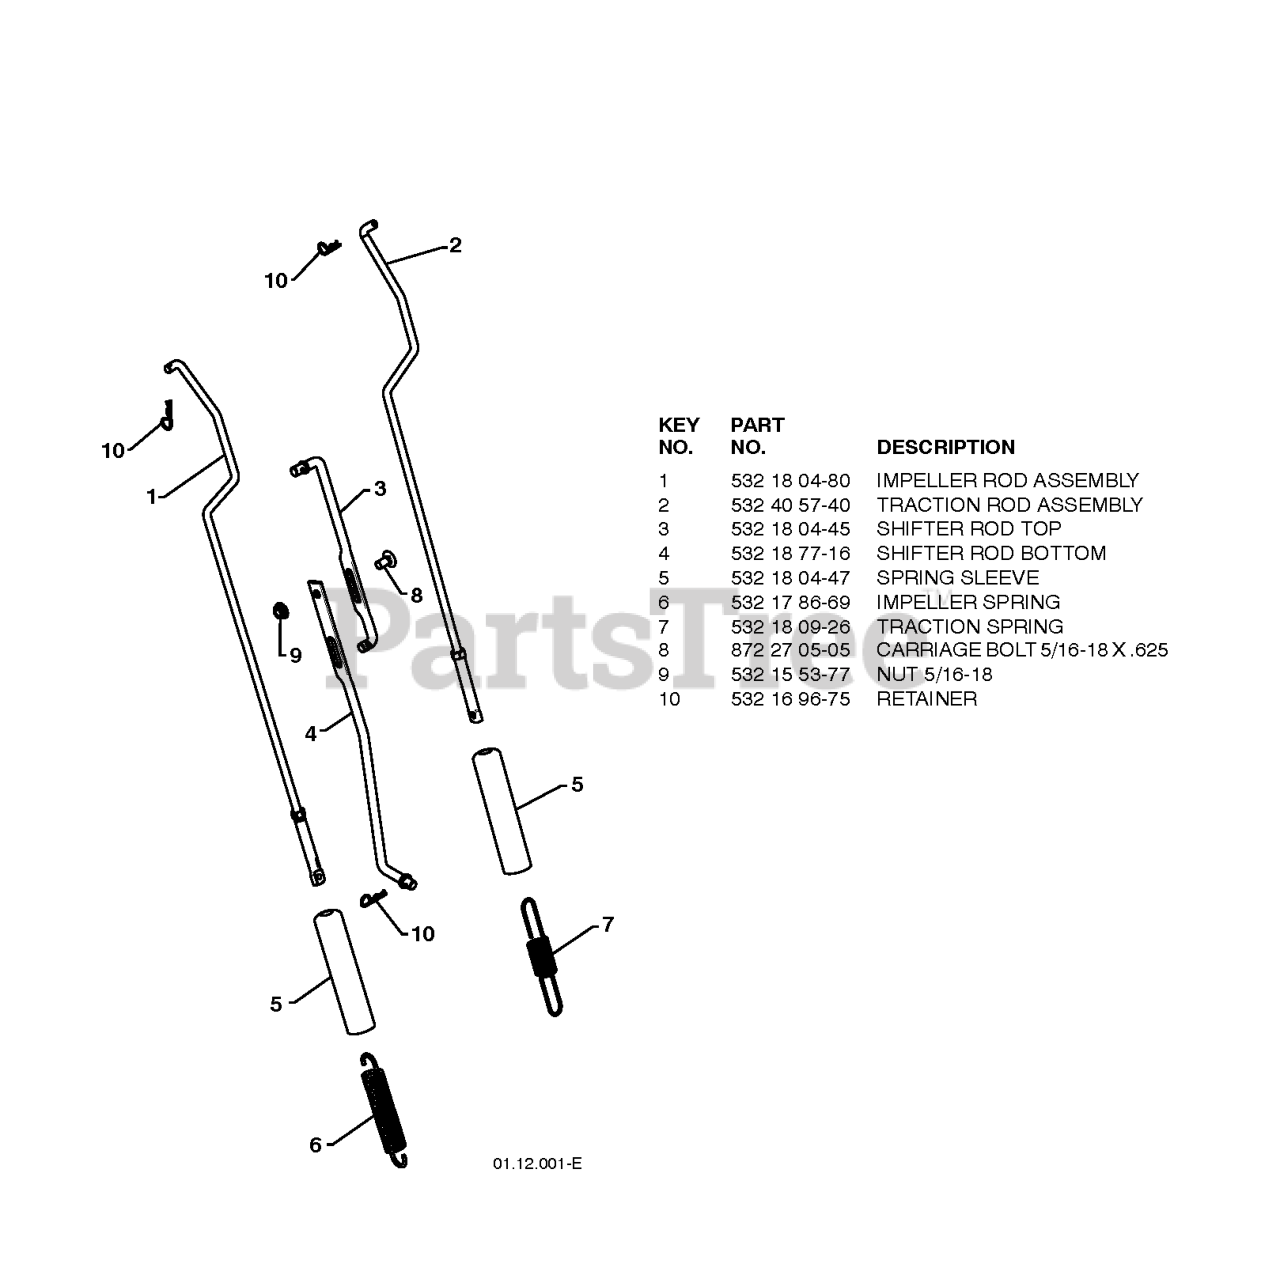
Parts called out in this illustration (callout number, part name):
1	ROD.ASM.IMPELLER
2	ROD.ASM.TRACTION
3	ROD, UPPER SPEED CONTROL
4	ROD, LOWER SPEED CONTROL.SNOW
5	SLEEVE, SPRING
6	SPRING, AUGER CONTROL
7	SPRING, TRACTION DRIVE
8	BOLT
9	NUT.FLANGE.5/16
10	SPRING RETAINER
